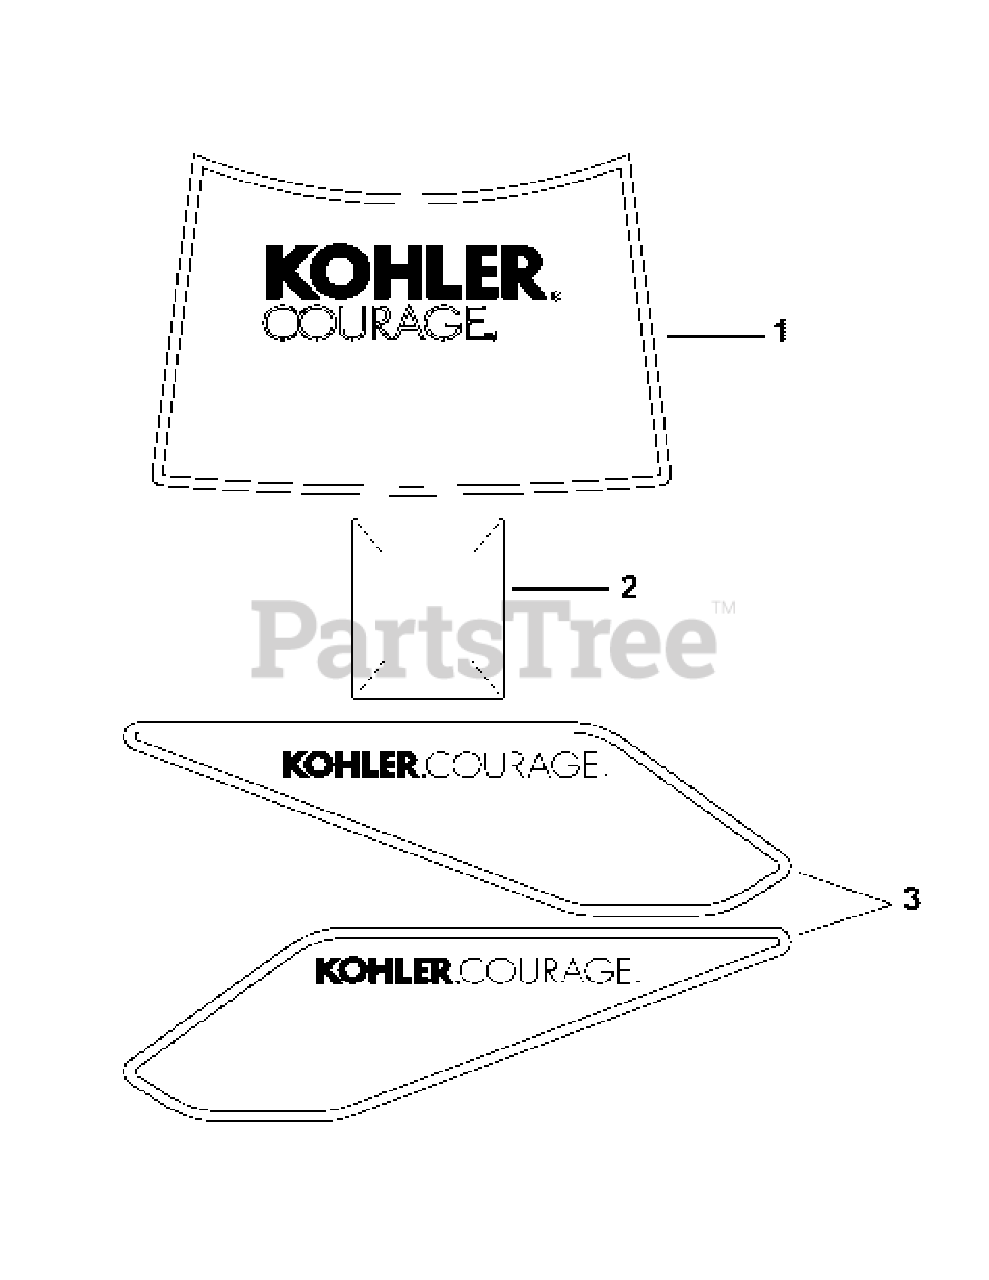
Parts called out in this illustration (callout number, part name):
1	23 HP Decal
2	Clear Laminate Decal
3	2-Piece Wing Set
